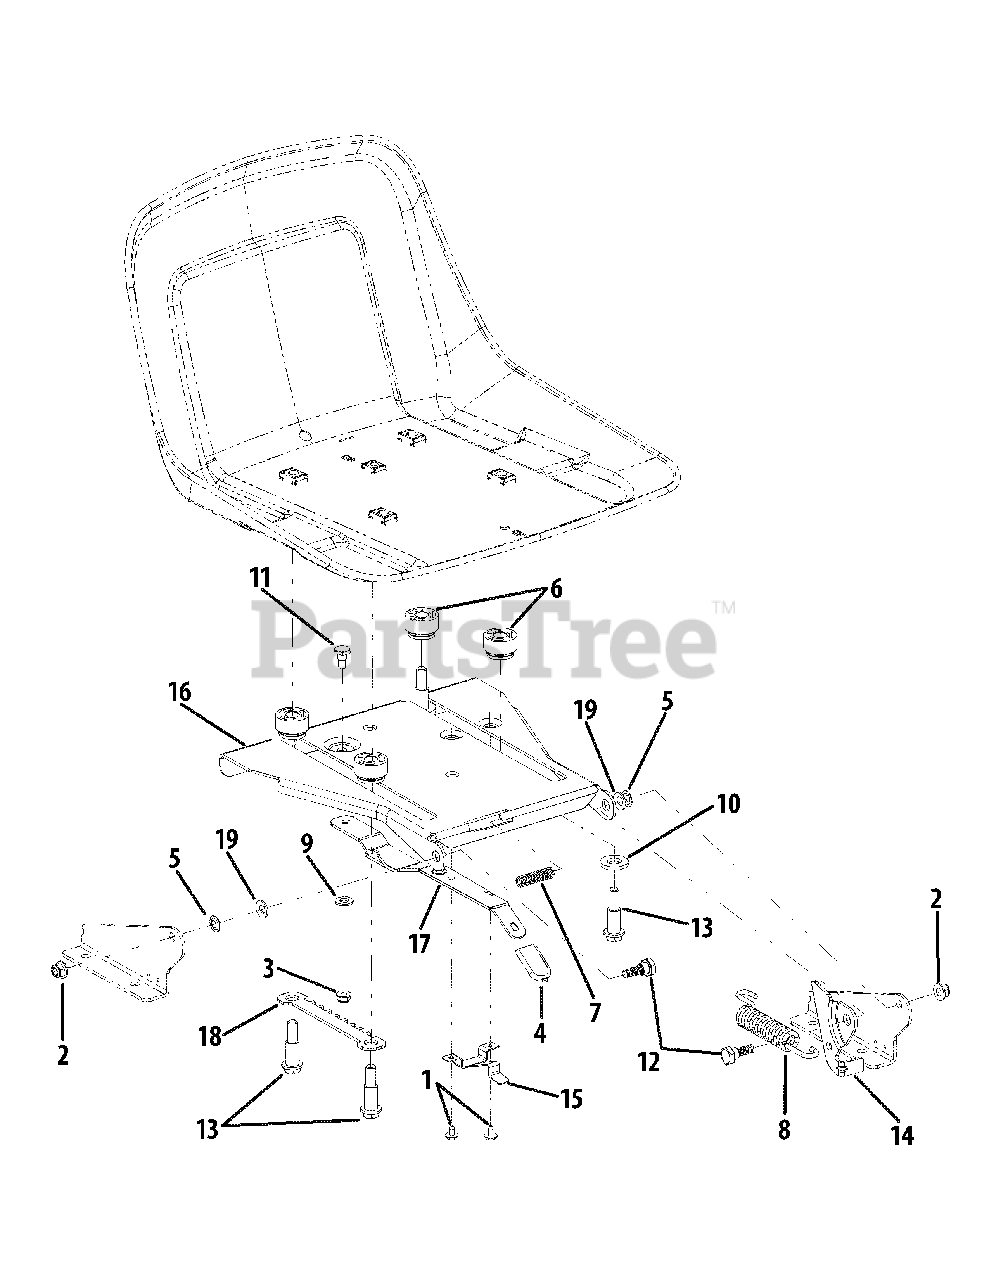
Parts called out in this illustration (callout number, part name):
1	Hex Screw, #10-16 x .375
2	Hex Insert Flange Lock Nut, 5/16-18
3	Hex Insert Flange Lock Nut,1/4-20
4	Seat Adjustment Grip
5	Speed Nut, .3125
6	Seat Adjustment Spacer
7	Compression Spring, .41 x 1.5
8	Extension Spring, .84 Dia. x 4.6
9	Flat Washer, .344 x .62 x .033
10	Flat Washer, .531 x 1.062 x .134
11	Shoulder Screw, .34 x .285 x 1/4-20
12	Shoulder Screw, .437 x .268 x 5/16-18
13	Shoulder Screw, .5 x .925 x 3/8 -16
14	Seat Lift Bracket
15	Seat Adjustment Stop
18	Seat Adjustment Index Bracket
19	Belleville Washer, .34 x .872 x .06
